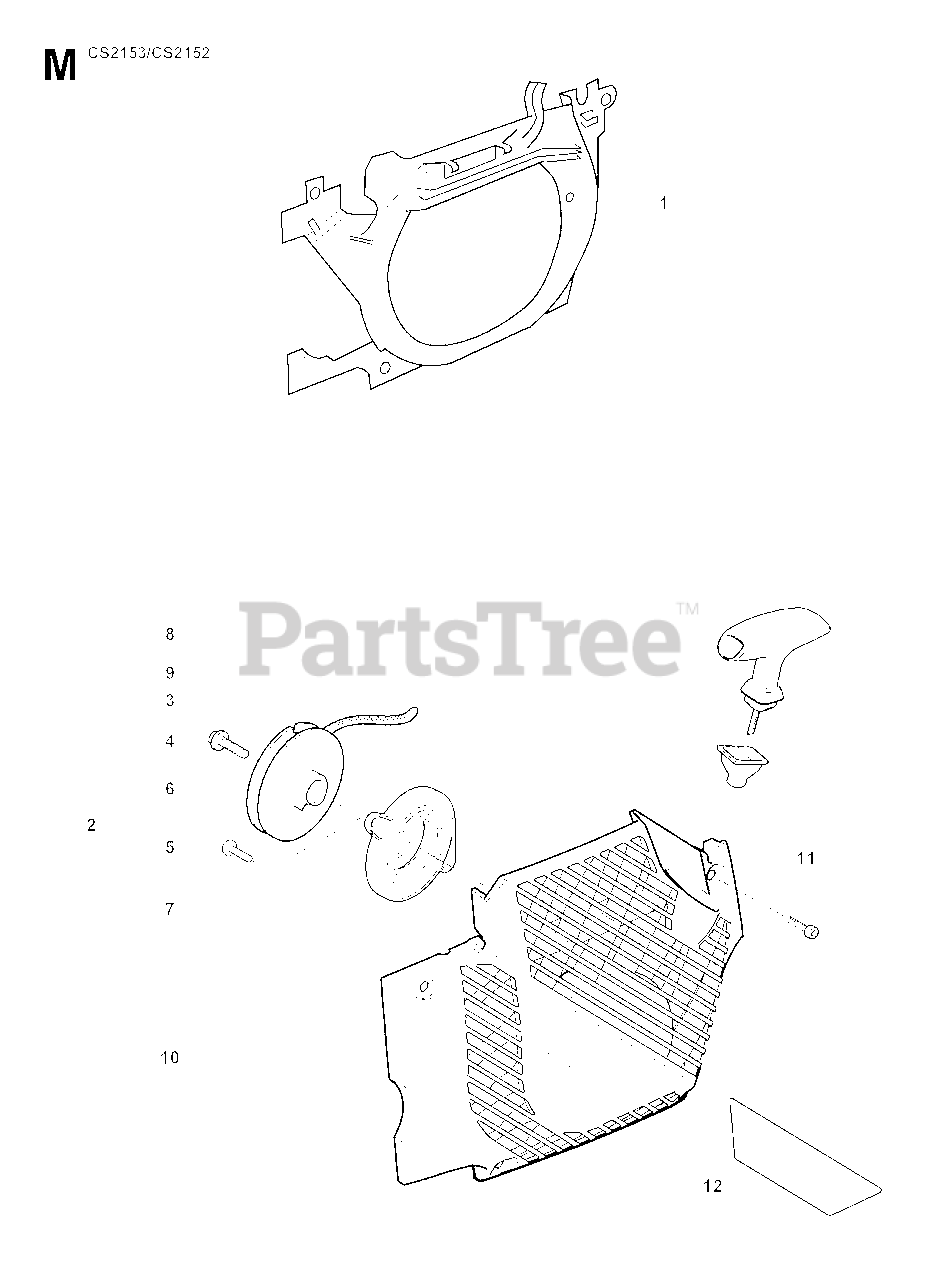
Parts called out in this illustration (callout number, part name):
1	AIR CONDUCTOR
2	STARTER ASSY.
3	STARTER ROPE
6	PULLEY
7	RETURN SPRING
8	STARTER HANDLE
10	STARTER HOUSING
12	LABEL
